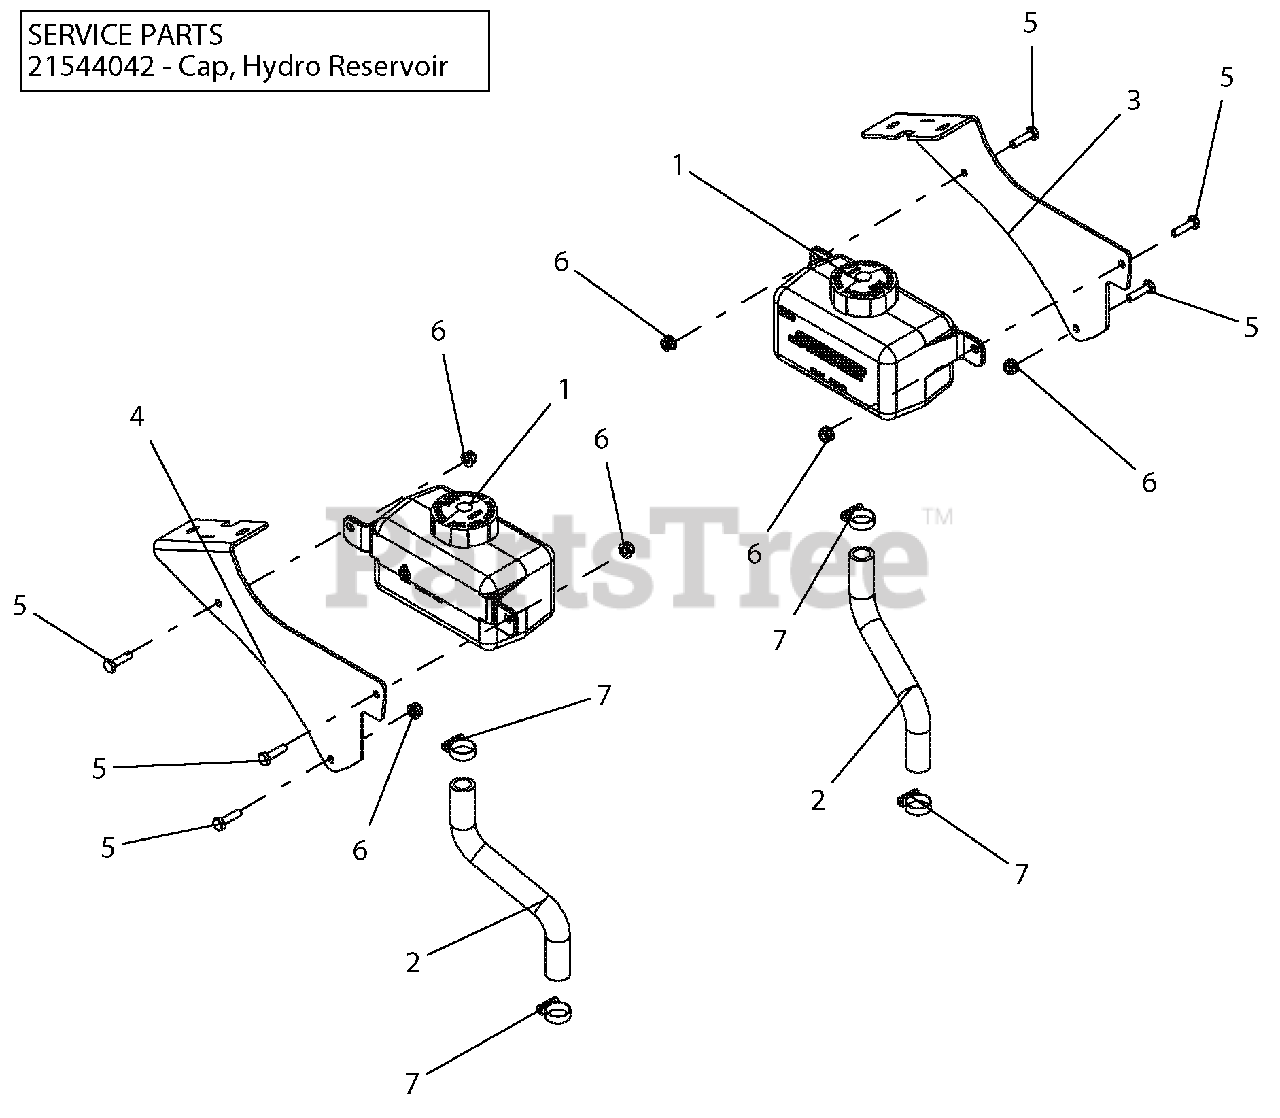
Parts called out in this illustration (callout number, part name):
1	TANK, HYD 1000ML
2	HOSE, HYDRO OVERFLOW
3	LH HYDRO OVERFLOW TANK CARB CANISTER MTG
4	BRKT, MOUNT RH HYDRO OVERFLOW TANK CARB CANISTER MTG
5	BLT-HEX .25-20X1.00 GR5 YWZC
6	NUT-LK-NYL-FLG .25-20 YWZC
7	CLAMP, .88 DIA HOSE
